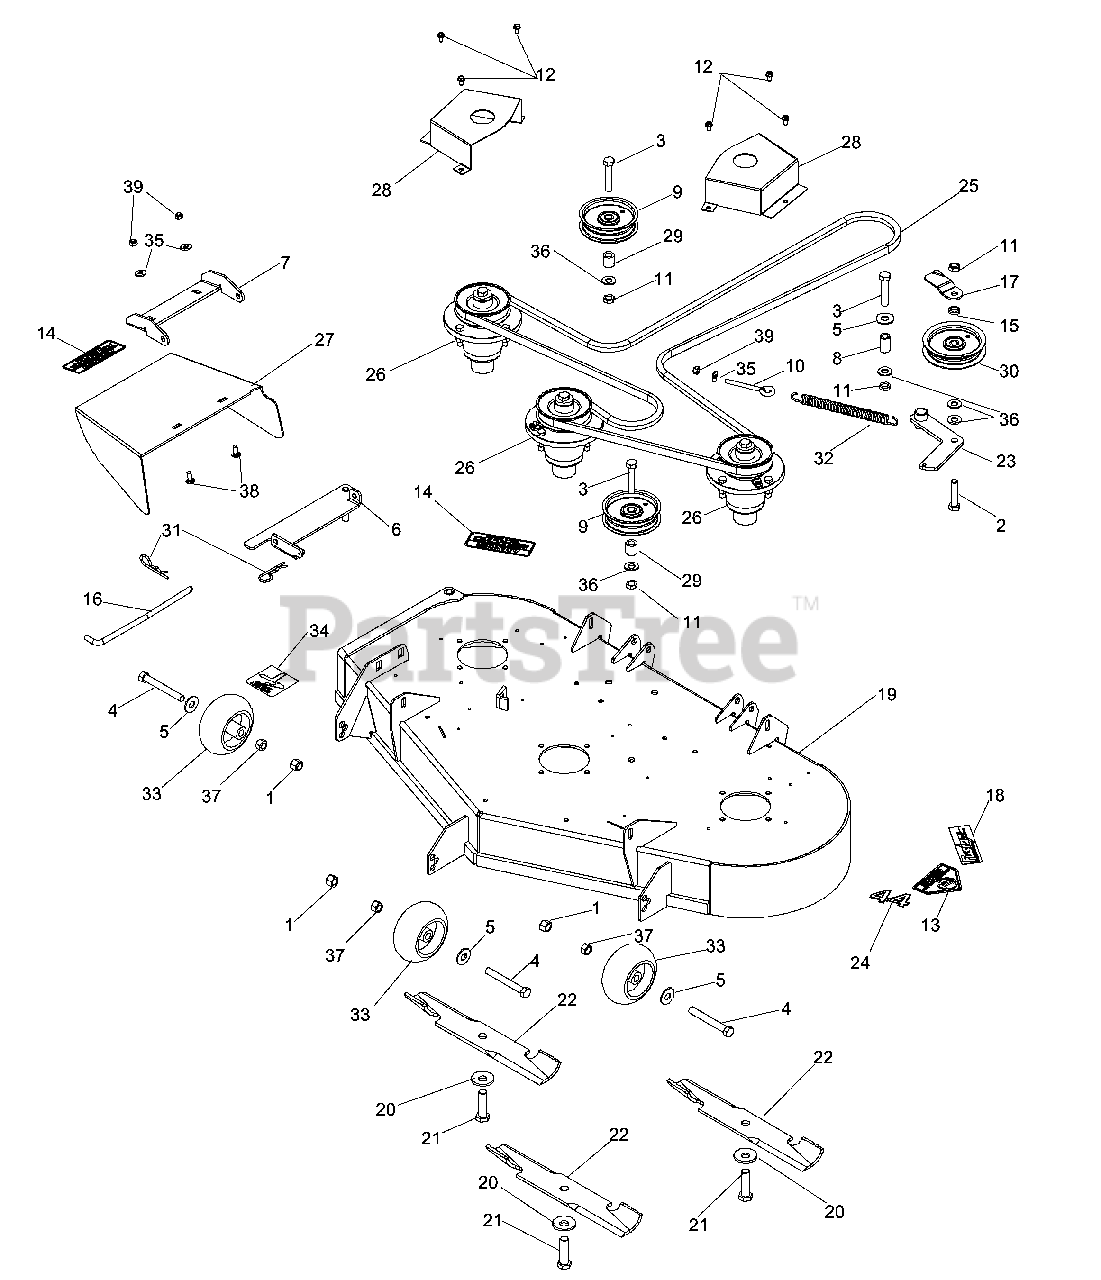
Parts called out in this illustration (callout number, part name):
1	NUT 1/2-13 HEX NYLOC ZD
2	HEX SCREW-.5C X 2.25
3	HEX SCREW 1/2-13 X 2.5" GR 5
4	HCS 1/2-13 X 4 GR 5 ZD
5	WASH USS FLAT 1/2
6	HINGE, 34, 44 - DK BLUE
7	CHUTE 44, DK BLUE
8	BUSHING DIXON 1080
9	PULLEY IDLER
10	EYE BOLT 5/16 X 3.50
11	NUT, 1/2-13 THIN PROF NYL
12	1/4-20 X 1/2 HWH FORM SCR H
13	WARNING LABEL DANGER
14	DECAL, DANGER
15	HD PULLEY SPACER
16	DEFLECTOR PIN
17	BELT GUARD BLK
18	DECAL, FUSION
19	200-076 NUT 1/2-20
20	BLADE WASHER
21	BLADE BOLT
22	BLD 44" HI LIFT FUS
23	IDLER ARM WLDT., BLACK
24	DECAL, DECK 44"
26	SPINDLE ASM.
27	DEFLECTOR MT. WLDT
28	PULLEY GUARD
30	IDLER PULLEY
31	5/32 X 3.0 HAIR PIN COTT
32	SPRING, DECK BELT
33	GUAGE WHEEL
34	DECAL, BELT ROUTING (18656)
35	FLAT WASHER 5/16 SAE
36	WASHER 1/2" FLAT
37	NUT HEX 1/2
38	BOLT 5/16C X 3/4" CARRIAGE
39	NUT 5/16 NYLOC
